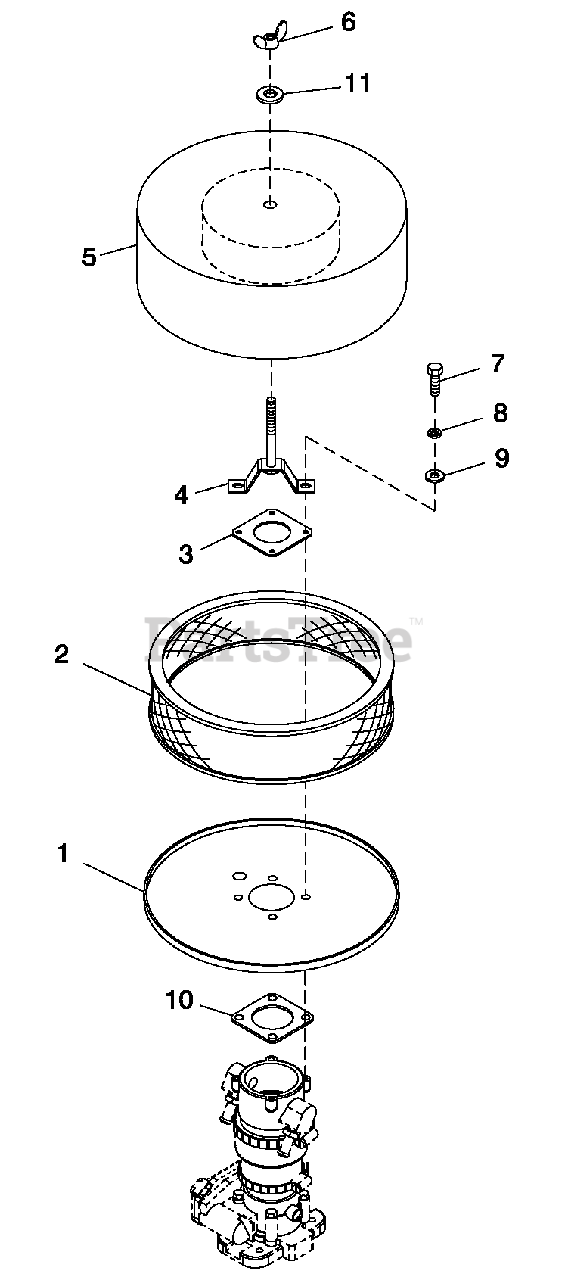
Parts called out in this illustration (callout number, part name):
1	AIR CLNR BTM PLT W/CPLR 8.1L
2	ELEMENT AIR FILTER
3	TOP PLATE VENTURI
4	HOLD DOWN AIR CLEANER PLATED
5	PLATE AIR CLEAN TOP 5.4L/6.8L
6	NUT WING 1/4-20 NYLK
7	SCREW HHC M6-1.0 X 16 G8.8
8	WASHER LOCK M6-1/4
9	WASHER FLAT M6
10	GASKET MIXER BODY
11	WASHER FLAT 1/4-M6 ZINC
